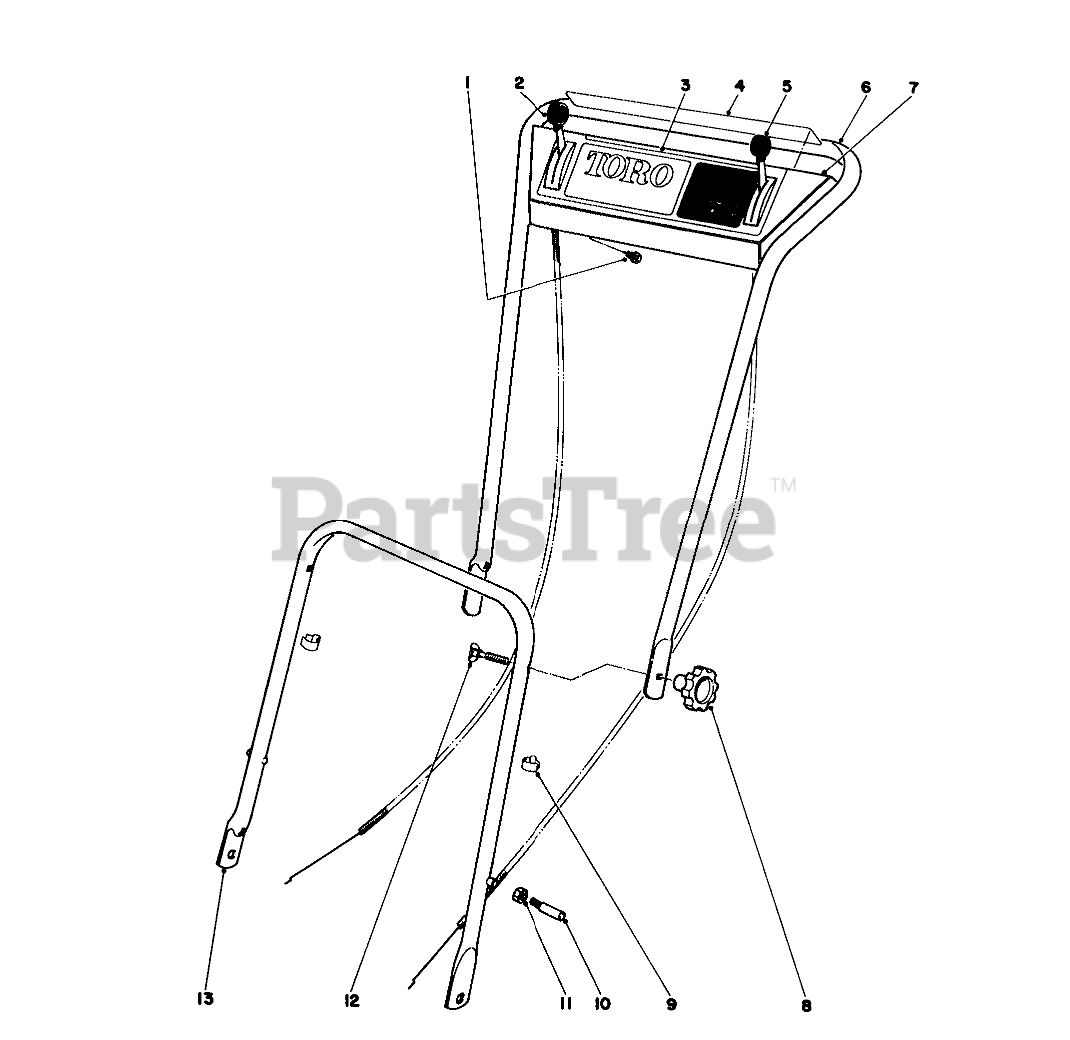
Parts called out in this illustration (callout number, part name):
1	SCREW-HWHTF
2	Control-Throttle
3	Decal, Escutcheon Plate (Model 16273)
4	Decal, Safety
5	Traction Control
6	UPPER HANDLE
7	Escutcheon Plate (Model 16273)
10	HANDLE PIN
11	Nut
12	SCREW-HANDLE
13	LOWER HDLE STKD ASM
